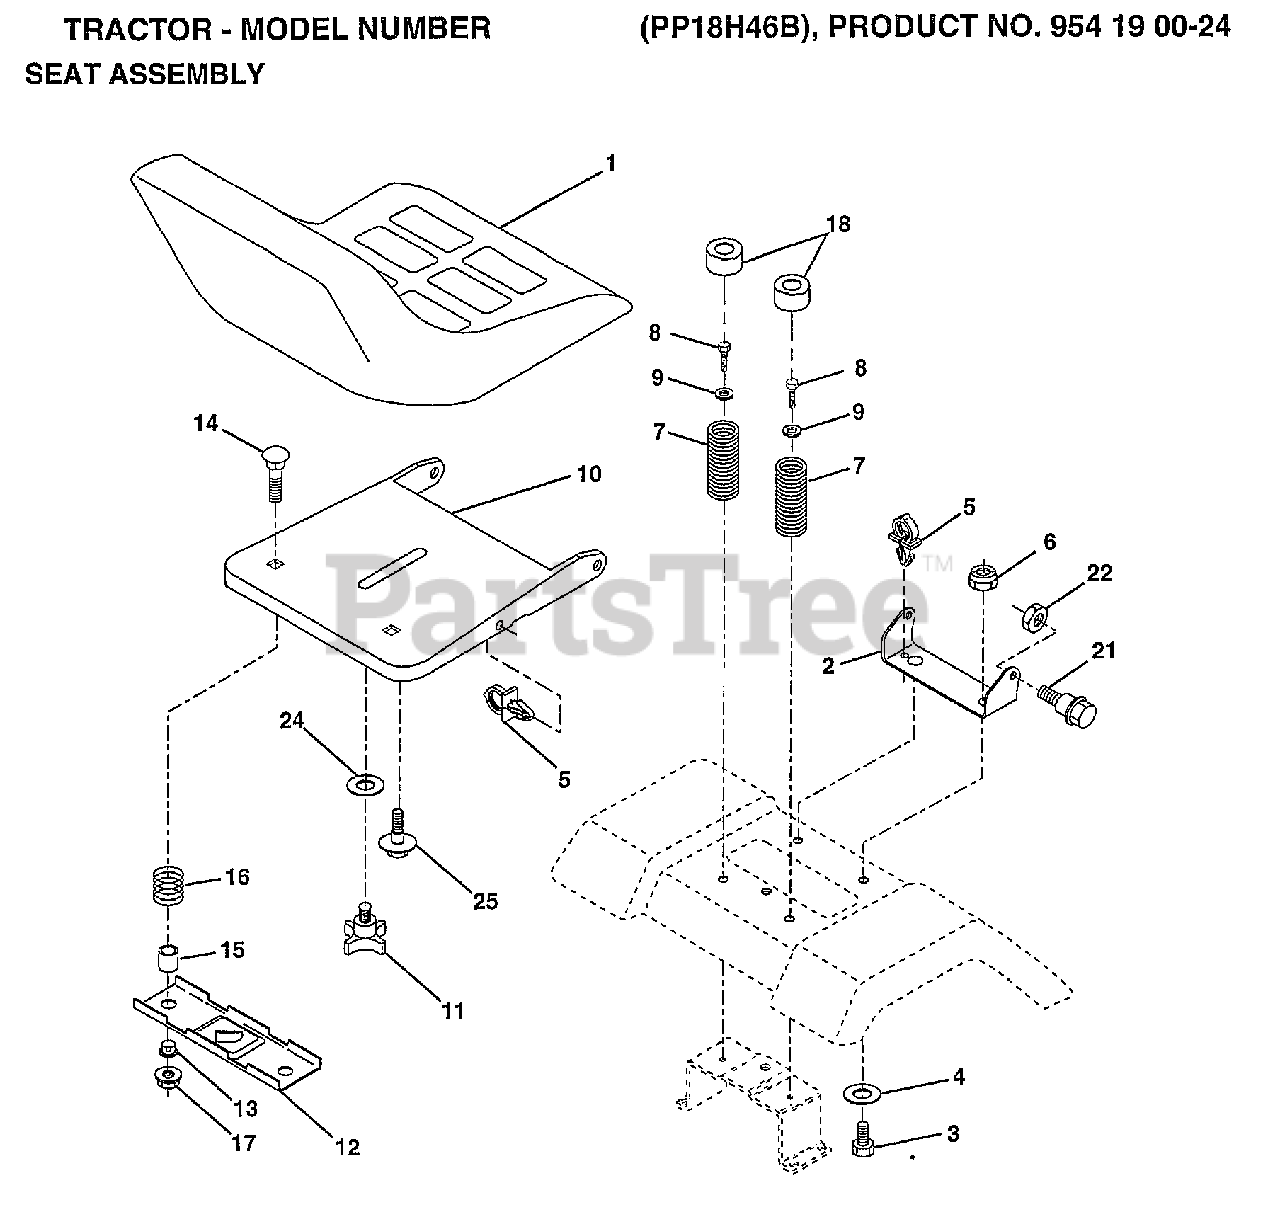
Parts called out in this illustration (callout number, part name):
1	SEAT.2500/1516.BK
2	BRACKET PVT SEAT
3	BOLT
4	WASHER PM
5	CLIP.PUSH-IN.HING
6	NUT
7	SPRING, COMPRESSION, SEAT
8	SCREW GTV
9	WASHER
10	PAN-SEAT
11	"KNOB 1/2"" YT"
12	BRKT SWITCH
13	BUSHING
14	BOLT-RD HD SQ NK
15	SPACER SPLIT
16	SPRING COMPRESSED
18	CAP SPRING
21	"BOLT,SHOULDER"
22	NUT
24	WASHER
25	"BOLT,SHOULDER"
